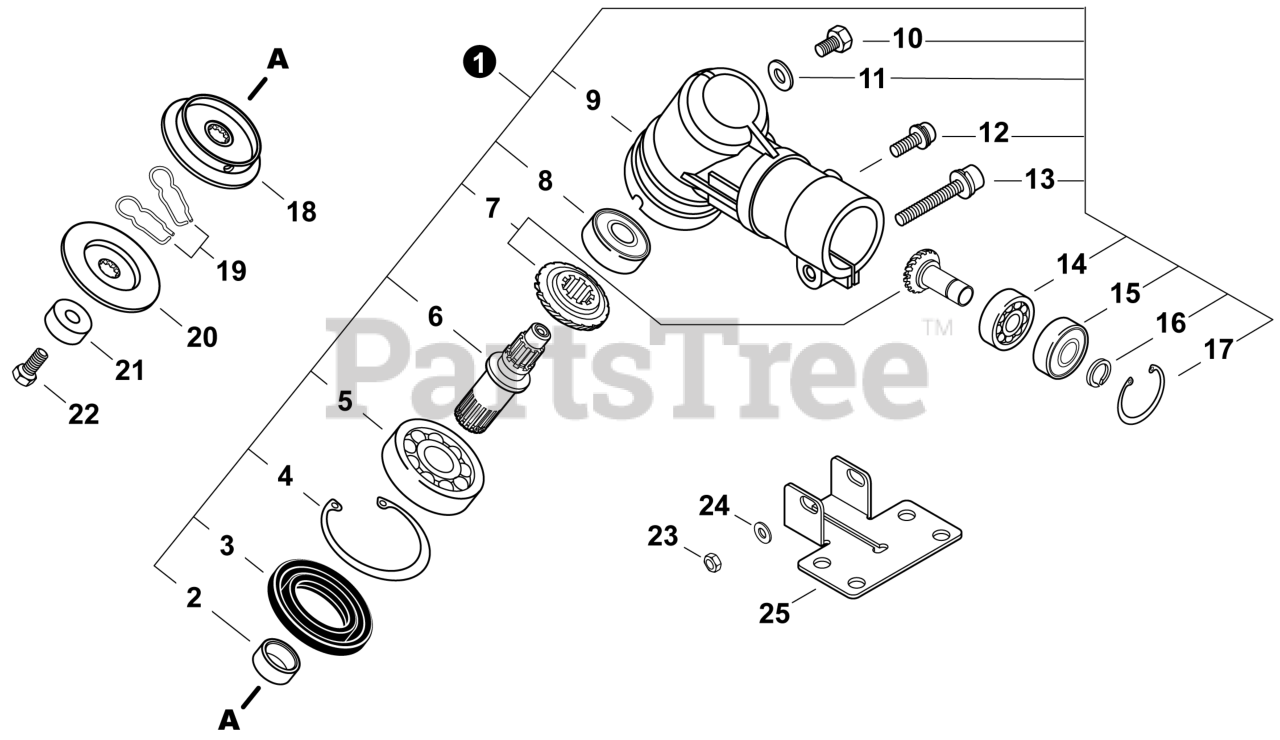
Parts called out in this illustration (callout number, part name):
1	GEAR CASE ASSY
3	SEAL, OIL
4	RING, SNAP 35
5	BEARING, BALL 6202
6	SHAFT, GEAR
7	GEAR SET, BEVEL
8	BEARING, BALL 6000DDU
9	HOUSING, GEAR CASE
10	BOLT M6x10
12	BOLT M6x14
13	BOLT M6x40
14	BEARING, BALL 6001
15	BEARING, BALL 6001ZZ
16	RING, SNAP 12
17	RING, SNAP 28
18	PLATE, ADAPTOR - UPPER
19	PIN, SLIDE
20	PLATE, ADAPTOR - LOWER
21	GUARD, BOLT
22	BOLT 10x37
23	NUT, HEX M6
24	WASHER 6.5x13x1
25	CLAMP, LOWER
